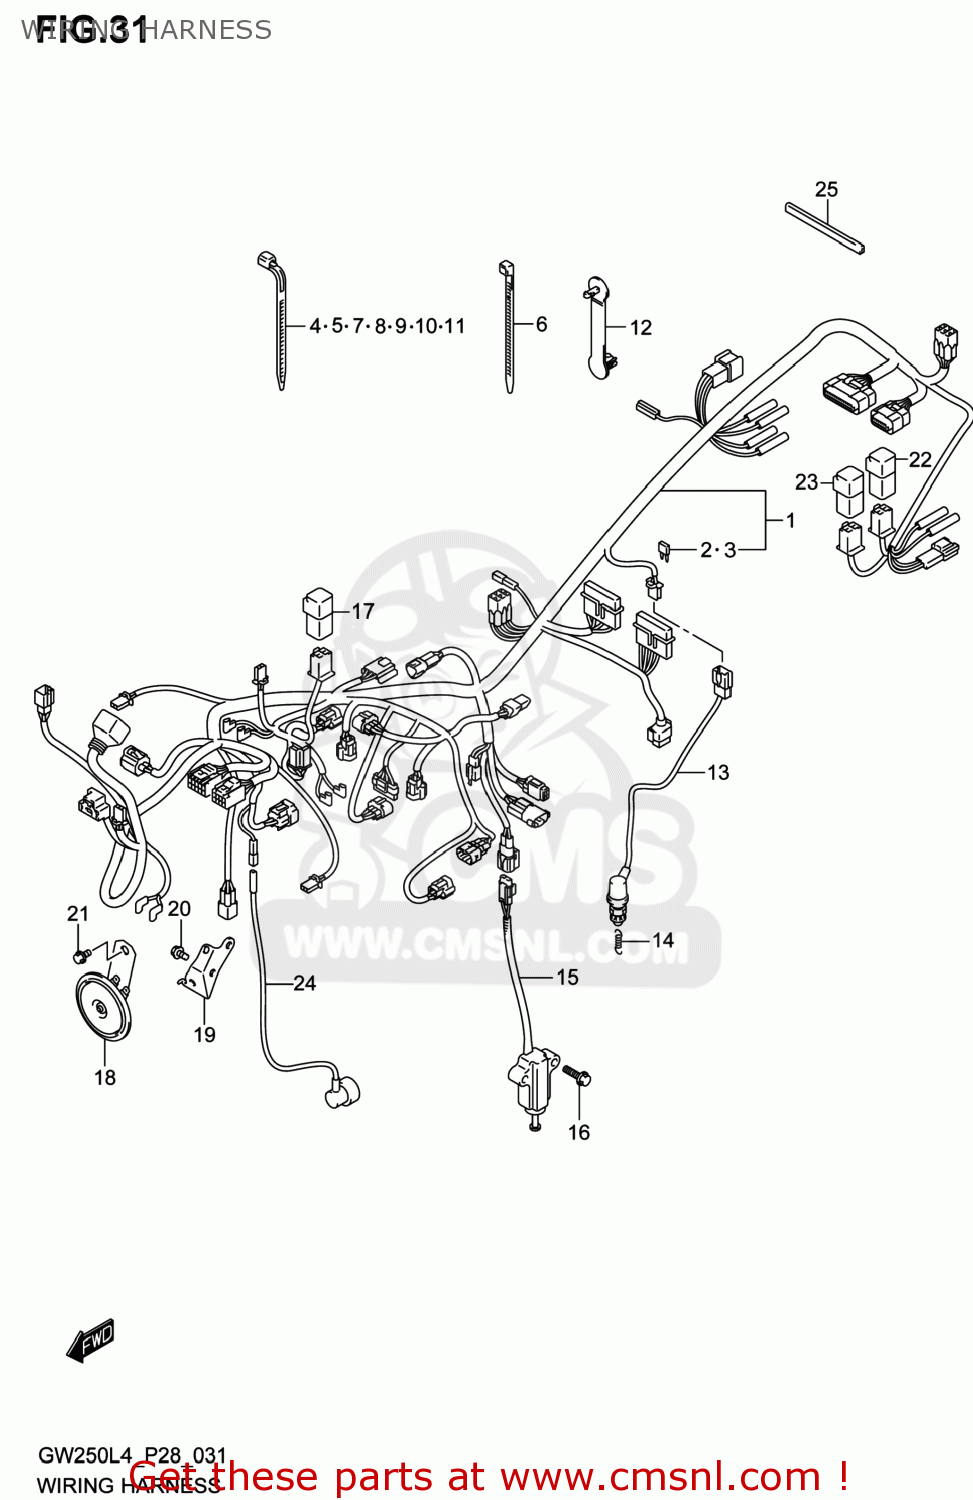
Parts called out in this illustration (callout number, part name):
1	HARNESS,WIRING
2	FUSE(10A)
3	FUSE(15A)
4	CLAMP,WIRING HARNESS
5	CLAMP,WIRING HARNESS
6	CLAMP(L:250)
7	CLAMP(L:235)
8	CLAMP,WIRING HARNESS
9	CLAMP,WIRING HARNESS
10	CLAMP(L:190)
11	CLAMP,WIRING HARNESS
12	CLAMP,WIRING HARNESS
13	SWITCH ASSY,STOP LAMP
14	SPRING
15	SWITCH ASSY,SIDE STAND
16	BOLT
17	RELAY ASSY,LAMP
18	HORN ASSY
19	PLATE,HORN
20	BOLT
21	BOLT
22	RELAY ASSY,LAMP
23	RELAY ASSY,LAMP
24	WIRE,OIL PRESSURE SWITCH LEAD
25	PROTECTOR,WIRING HARNESS
